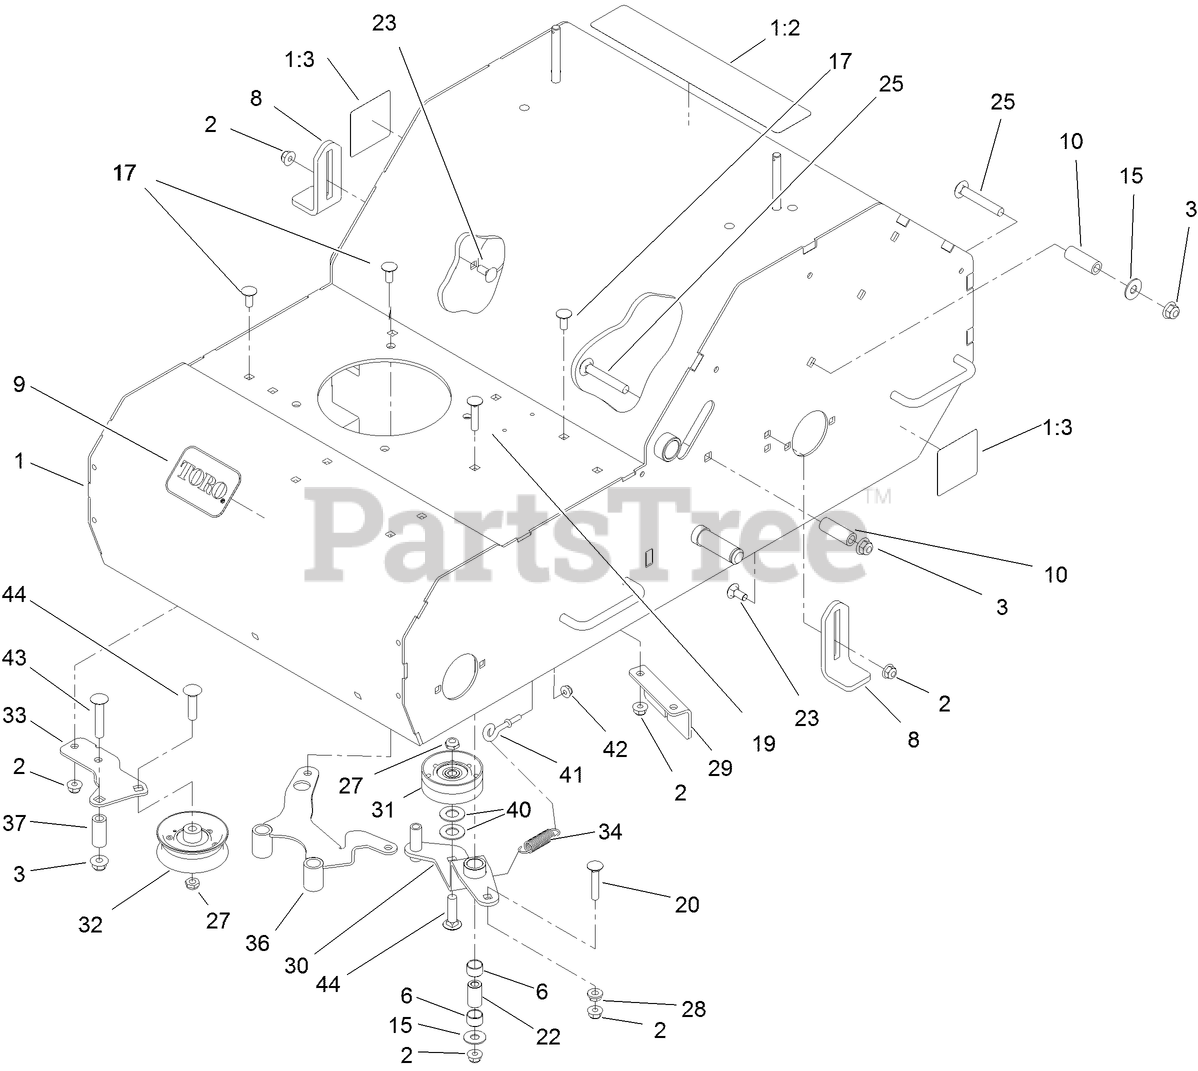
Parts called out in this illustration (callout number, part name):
1	FRAME ASM
1:2	DECAL-WARNING, AERATOR
1:3	DECAL-WARNING
2	NUT-HF, NI
3	NUT-HF, NI
6	BEARING
8	STOP-DEPTH
9	DECAL
10	SPACER
15	WASHER-FLAT
17	SCREW-CARR
19	BOLT-CARR
20	SCREW-CARR
22	BUSHING-ARM, IDLER
23	BOLT-CARR
25	SCREW-CARR
27	NUT-LOCK, NI
28	NUT-HF
29	BRACKET-MOUNT, CABLE
30	ARM-IDLER
31	PULLEY
32	PULLEY-IDLER, FLAT
33	BRACKET-MOUNT, PULLEY
34	SPRING-EXTENSION
36	GUIDE-BELT
37	SPACER
40	WASHER
41	BOLT-EYE
42	NUT-HF
43	BOLT-CARRIAGE
44	SCREW-CARR
